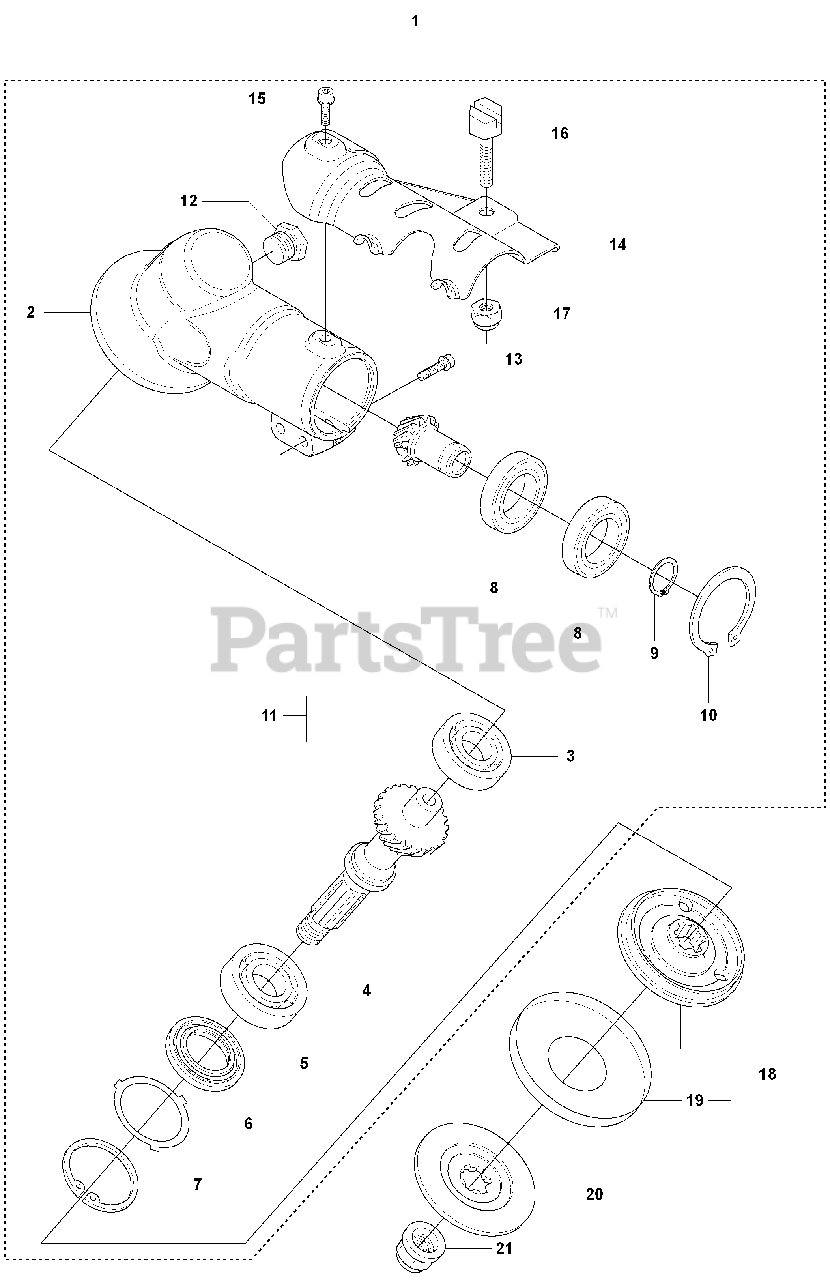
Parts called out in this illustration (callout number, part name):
2	GEAR HOUSING
3	BALL BEARING
4	BALL BEARING
7	RETAINING RING SGH 35
8	BALL BEARING
9	RETAINING RING SGA 15
10	RETAINING RING
11	BEVEL GEAR
14	ATTACHMENT PLATE
17	LOCKNUT M6
19	GRASS SEALING
20	SUPPORT FLANGE
21	BLADE NUT
